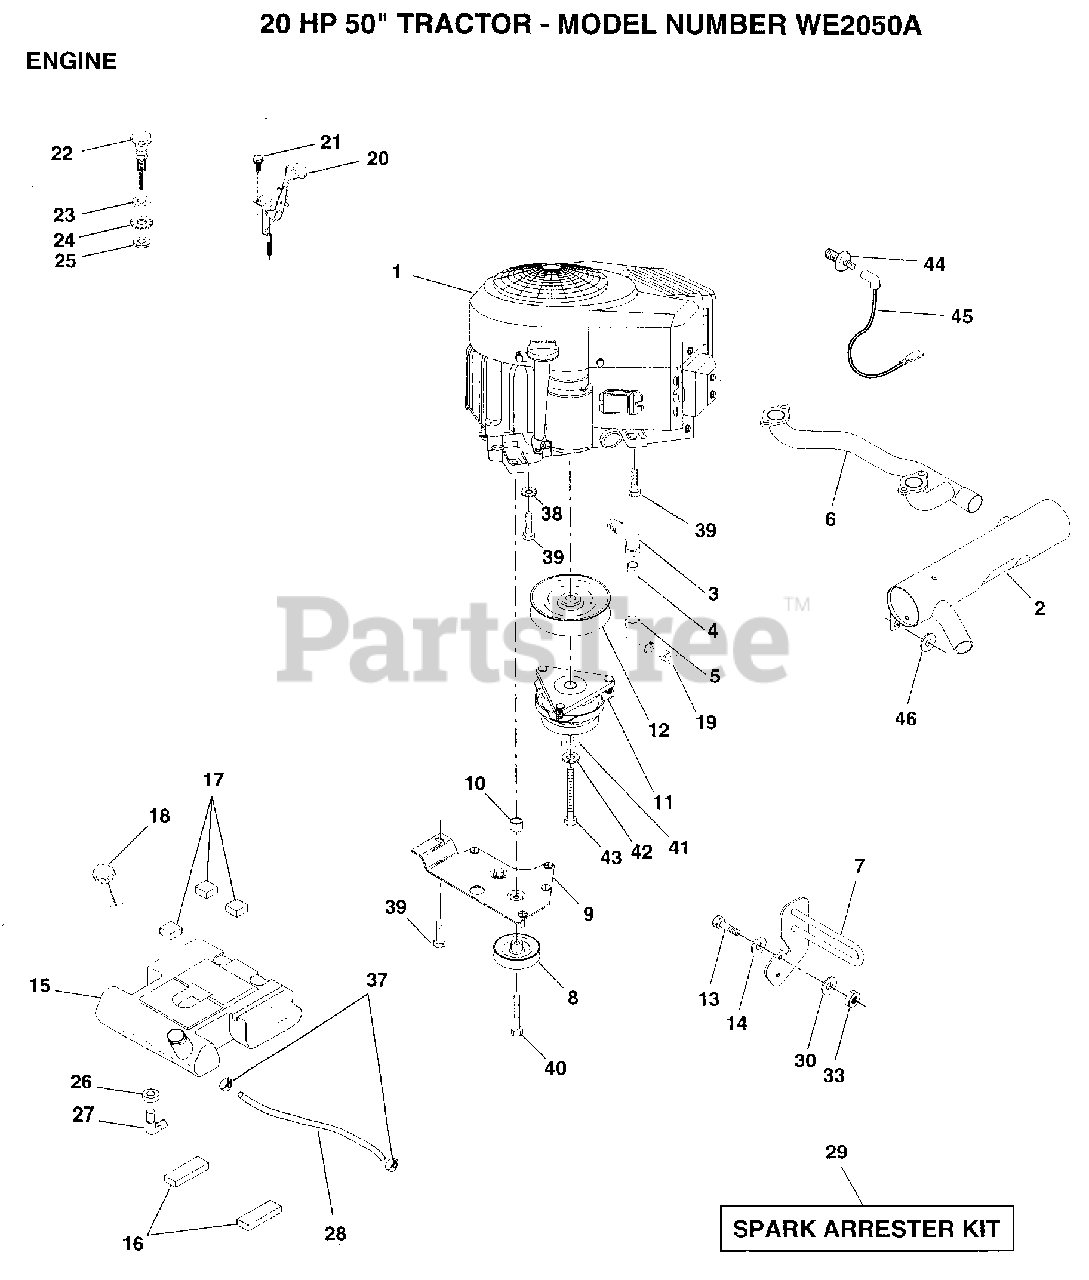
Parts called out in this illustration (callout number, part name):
2	BRACKET.ACTUAT.LH
3	STREET ELBOW LT
4	PIPE NIPPLE
5	ELBOW
6	PIPE.EXHAUST.B&S
12	PULLEY.ENGINE.VGT
13	"BOLT,HEX"
14	WASHER
16	PAD IDLER TI
17	PAD-SPACER LT
19	PLUG T
20	CONTROL.TRTL.37
21	SCREW LT
22	CHOKE CONTROL
23	WASHER
24	LOCKWASHER
26	BUSHING OUTLET T
29	SPARK ARREST KIT
30	WASHER T
33	NUT
38	LOCKWASHER
39	SCREW LT
40	SCREW.3/8-16X3.25
41	WASHER
42	LOCKWASHER
44	WIRE.LEAD.SENTRY
46	WASHER HYT
